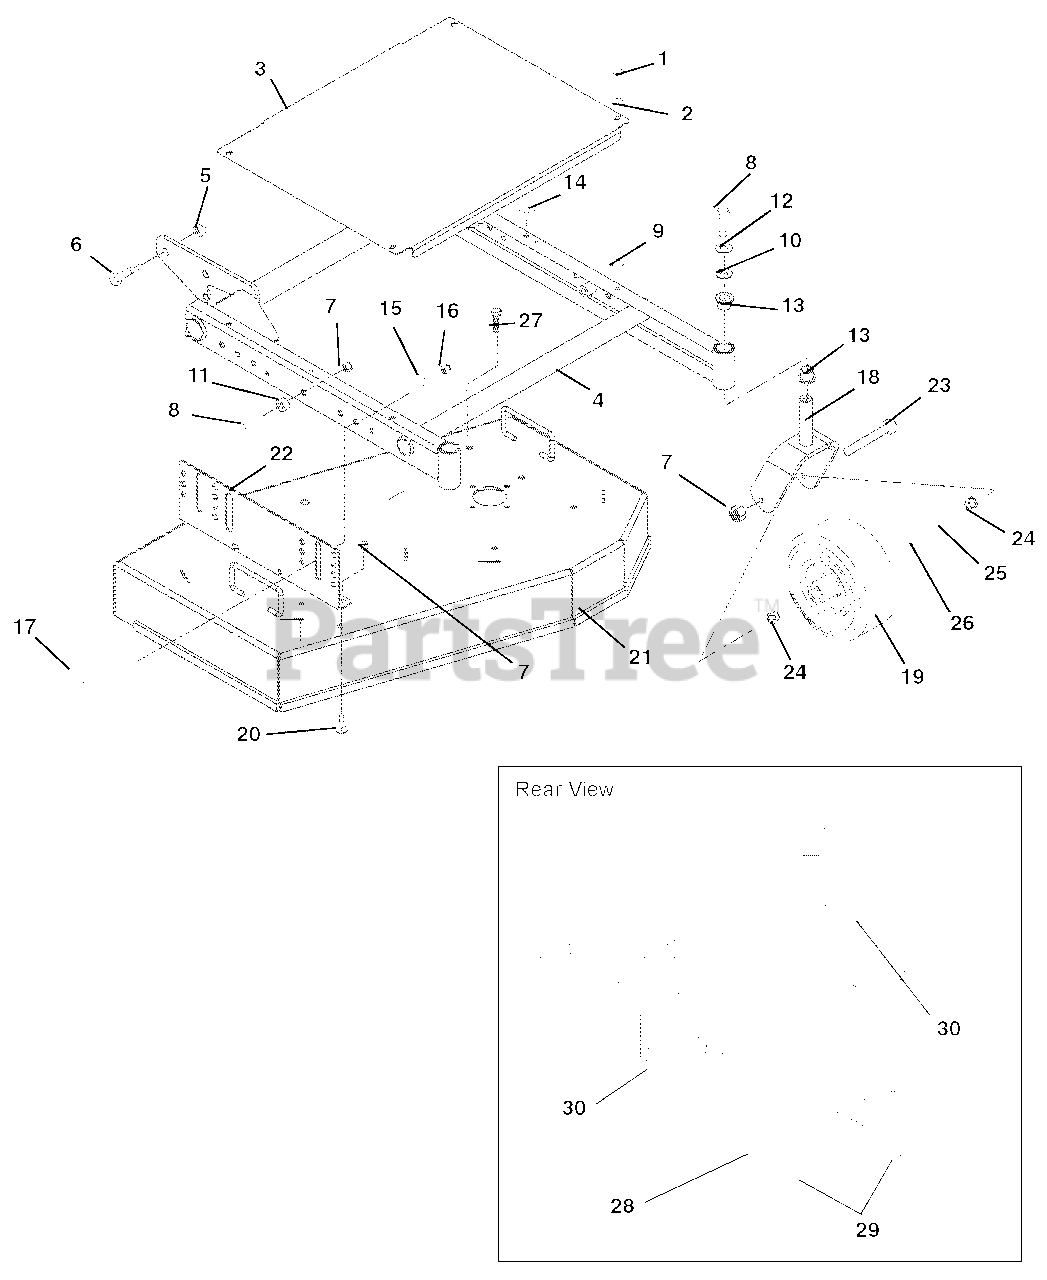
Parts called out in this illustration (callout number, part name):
1	@SCR-TAP .25-20X.50 HWH TR YWZ
2	@WSHR-FL-STL.281X.62X.065 YWZC
3	COVER - BELT - PRO - 32"
4	WMT - MOWER FRAME - 32"
5	@NUT-LK-NYL .625-11 YWZC
6	@BLT-HEX .62-11X1.50 GR5 YWZC
7	@NUT-LK-TOP-FLG .38-16 YWZC
8	@BLT-HEX .38-16X1.25 GR5 YWZC
9	GRMT,PLASTIC
10	WSHR-FL-STL .380X1.50X.125YWZC
11	BSHG-SLV .391X.688X.52 PM
12	@WSHR-LK .38X.094 REG YWZC
13	BSHG-FLG 1.00X1.25X1.50X1.50EP
14	BUMPER GROMMET
15	SPRG, COMP .058X.65X2.13 WLD15
16	@NUT-LK-CTR .50-13 YWZC
17	PIN - LATCH
18	WMT - CASTER FORK
19	WHEEL 9 X 3.50 SEMI-PNEUMATIC
20	@BLT-RDHDSQNK .38-16X1.00 G5YZ
21	KIT-32" REAR DIS DECK W/DECALS
22	KIT-MOWER SIDE SUPT BRKT-RH&LH
23	BLT-HEX .38-16X5.50 YWZC
24	RTNR-BEARING-PRO
25	BEARING .625 X .380 X 4.08
26	BEARING, ROLLER--PRO
27	@BLT-HEX .38-16X1.00 GR5 YWZC
28	WMT-32" DEFLECT EXT-REAR DISCH
29	@BLT-HEX .31-18X.75 GR5 YWZC
30	@NUT-LK-TOP-FLG .31-18 YWZC
